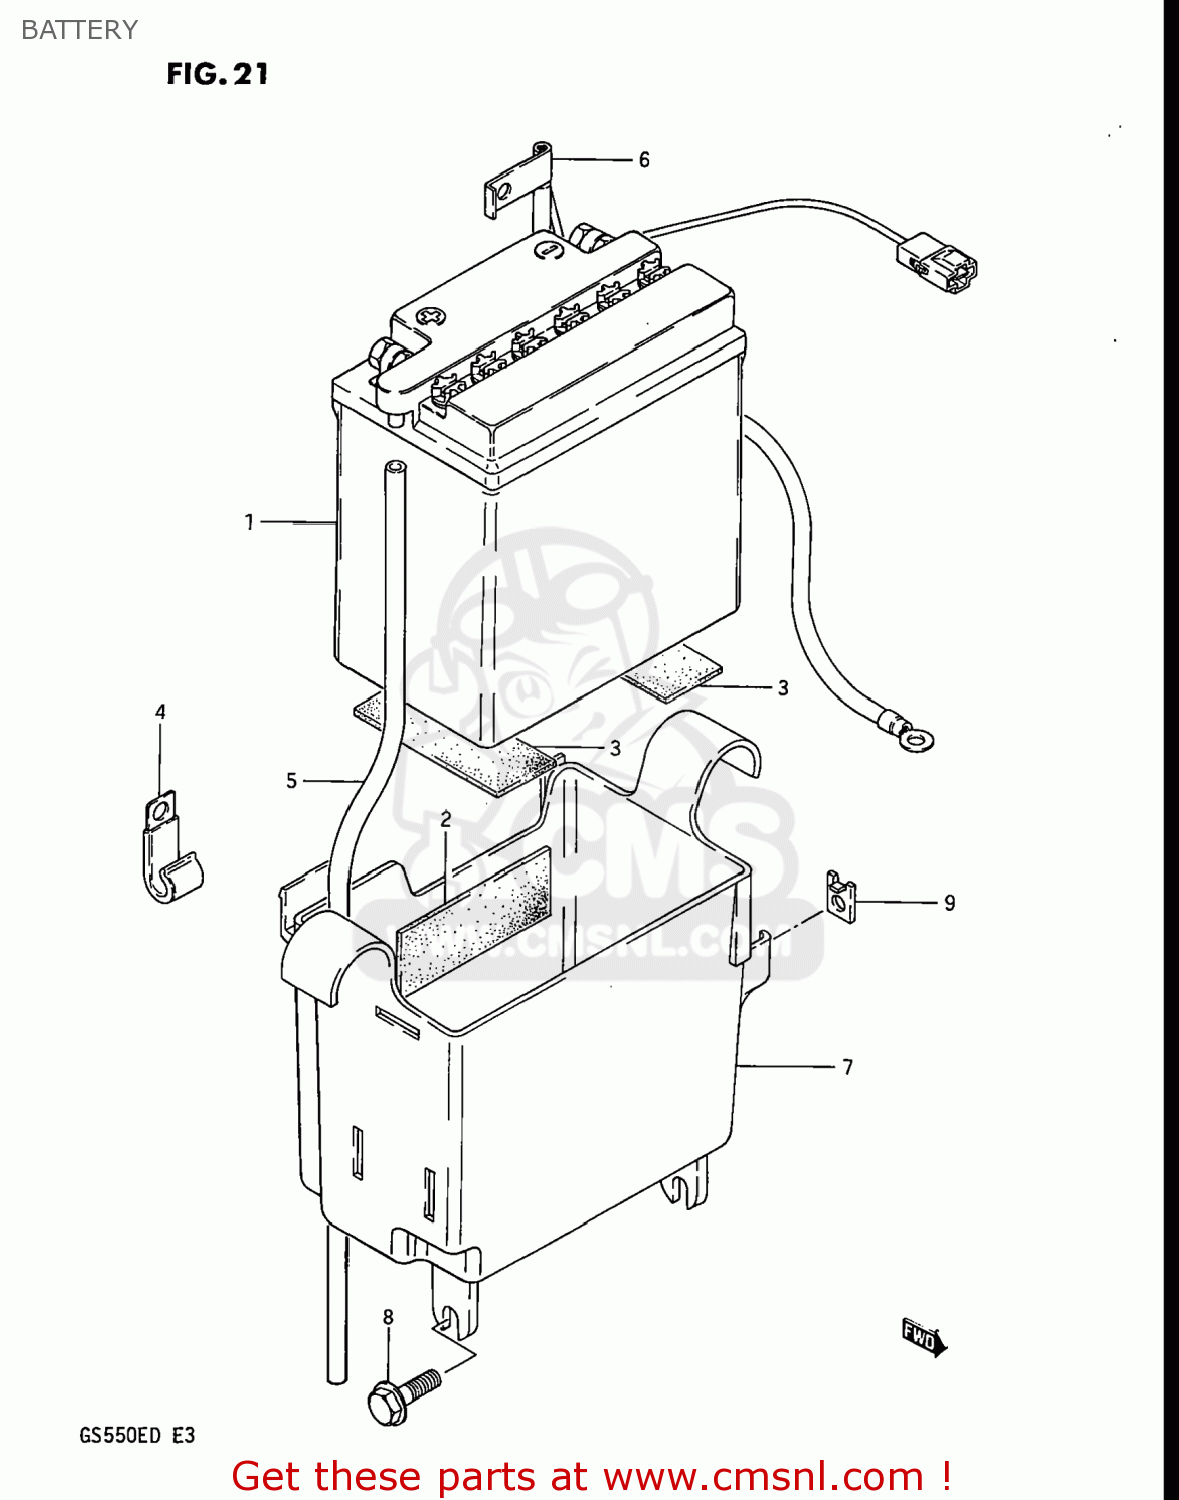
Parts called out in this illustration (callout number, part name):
1	BATTERY ASSEMBLY (12V)
2	PROTECTOR(30X80X2)
3	PROTECTOR,20X9
4	CLAMP
5	HOSE,BATTERY EXHAUST
6	WIRE,STARTER MOTOR LEAD
7	HOLDER,BATTERY
8	BOLT
9	WASHER,IGNITER
